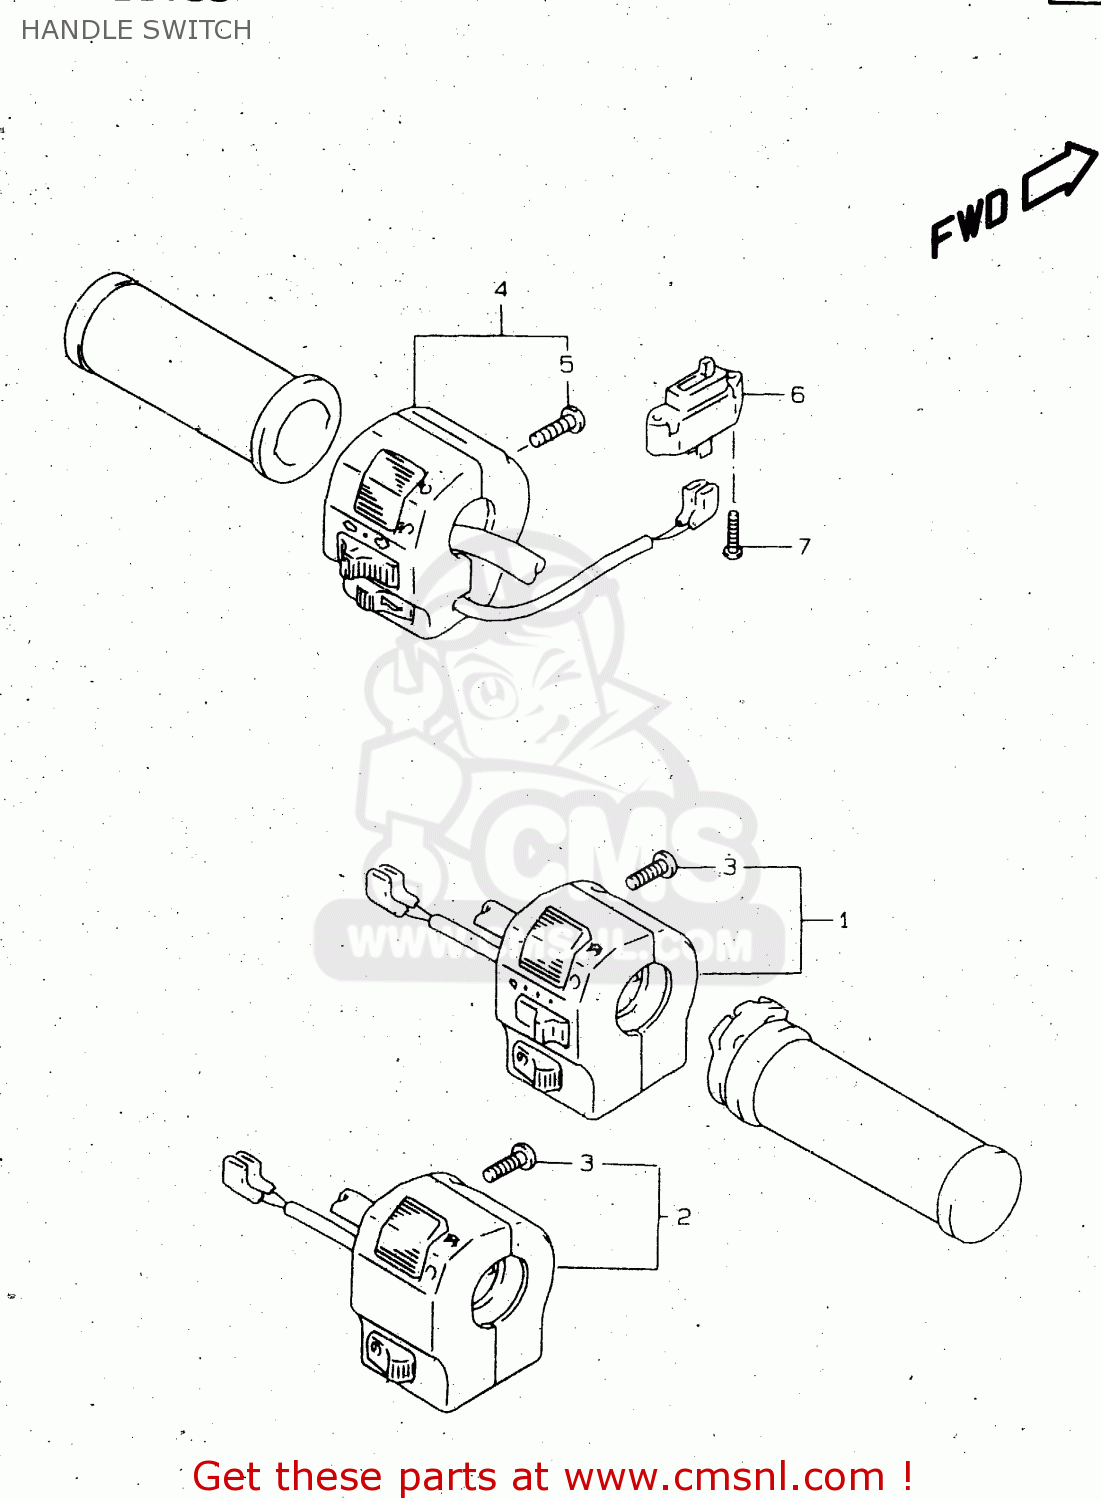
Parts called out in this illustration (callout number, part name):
1	SWITCH ASSY,HANDLE,R
2	SWITCH ASSY,HANDLE,R
3	SCREW
4	SWITCH ASSY,HANDLE,L
5	SCREW
6	SWITCH ASSY,CLUTCH
7	SCREW
